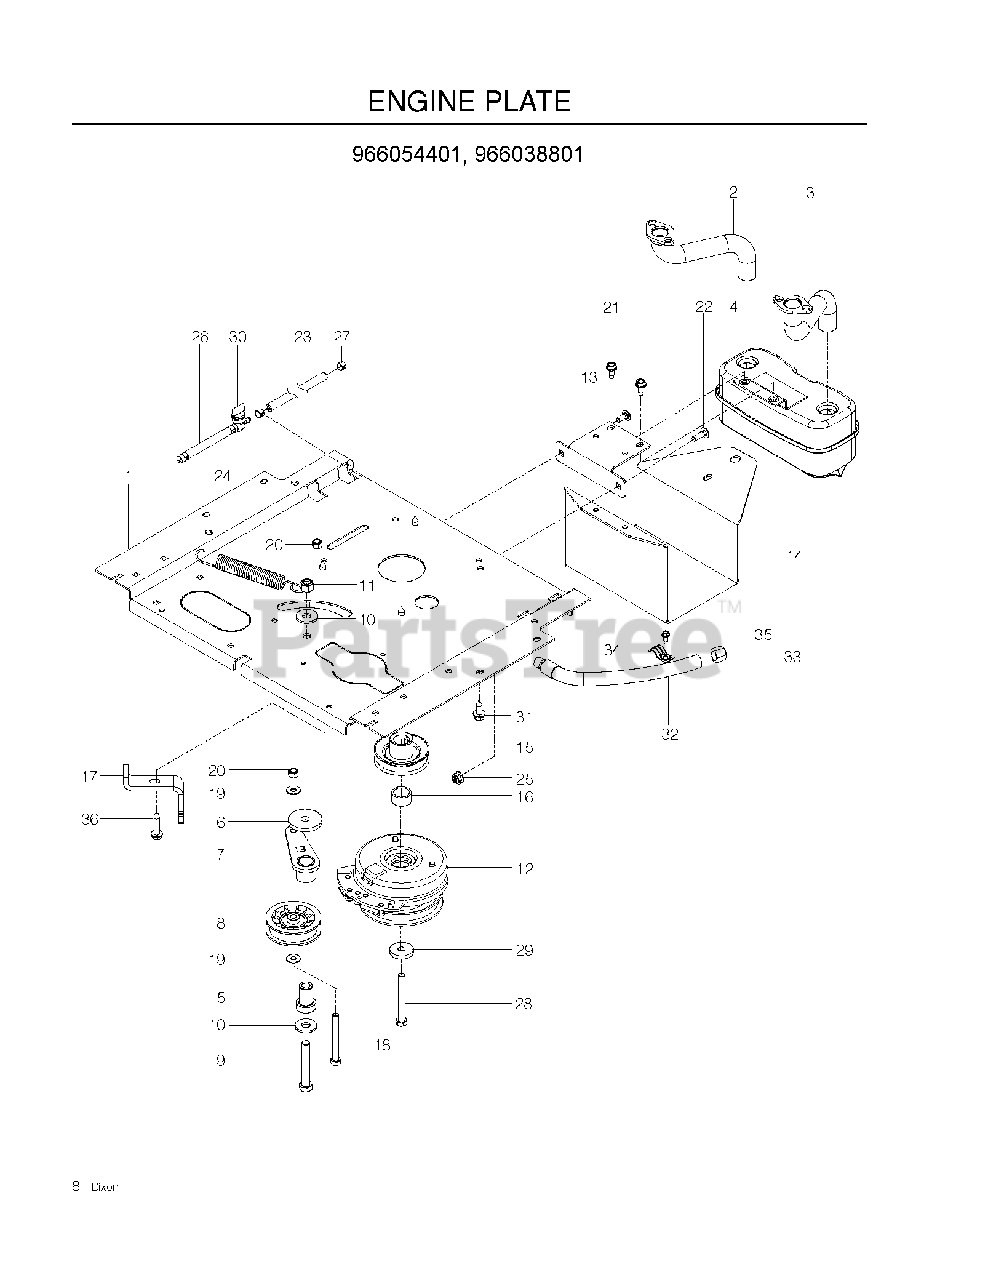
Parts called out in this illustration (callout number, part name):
1	PLATE, ENGINE, BLACK
2	RP.EXHAUST.TUBE.LH.BS/TWIN
3	RP.EXHAUST.TUBE.RH.BS/TWIN
4	MUFFLER ASM TWIN
5	IDLER SPINDLE
6	HEAVY WASHER
7	IDLER ARM WELDMENT
8	PULLEY, IDLER
9	HCS 1/2C X 3 1/4
10	WASH USS FLAT 1/2
11	NUT 1/2-13 HEX NYLOC ZD
12	CLUTCH, 105 FT-LBS
13	BRACKET, MUFFLER, BLACK
14	GUARD, MUFFLER, BLACK
15	PULLEY, ENGINE
16	T & B SPACER
17	STOP, CLUTCH BLK
18	HCS 3/8-16X3 1/2 GR5
19	WASHER 5/16 FLAT
20	NUT 3/8-16 NYLOC
21	BOLT 5/16-18 X 3/4
22	BOLT 5/16C X 3/4" CARRIAGE
24	SPRING, DECK DRIVE
25	5/16-18 NYLOC FLANGE NUT
26	HOSE 1/4 X 8
27	HOSE CLAMP
28	HCS 7/16-20X3-1/2 GR 5 ZN
29	CLUTCH, WASHER
30	FUEL VALVE
31	HHFS 3/8-16 X 1.0 THD FORMING
32	OIL DRAIN HOSE
33	DRAIN CAP
35	SCREW 1/4 X 5/8
36	BOLT 3/8-16 X 1 1/2 ZINC CLEAR
